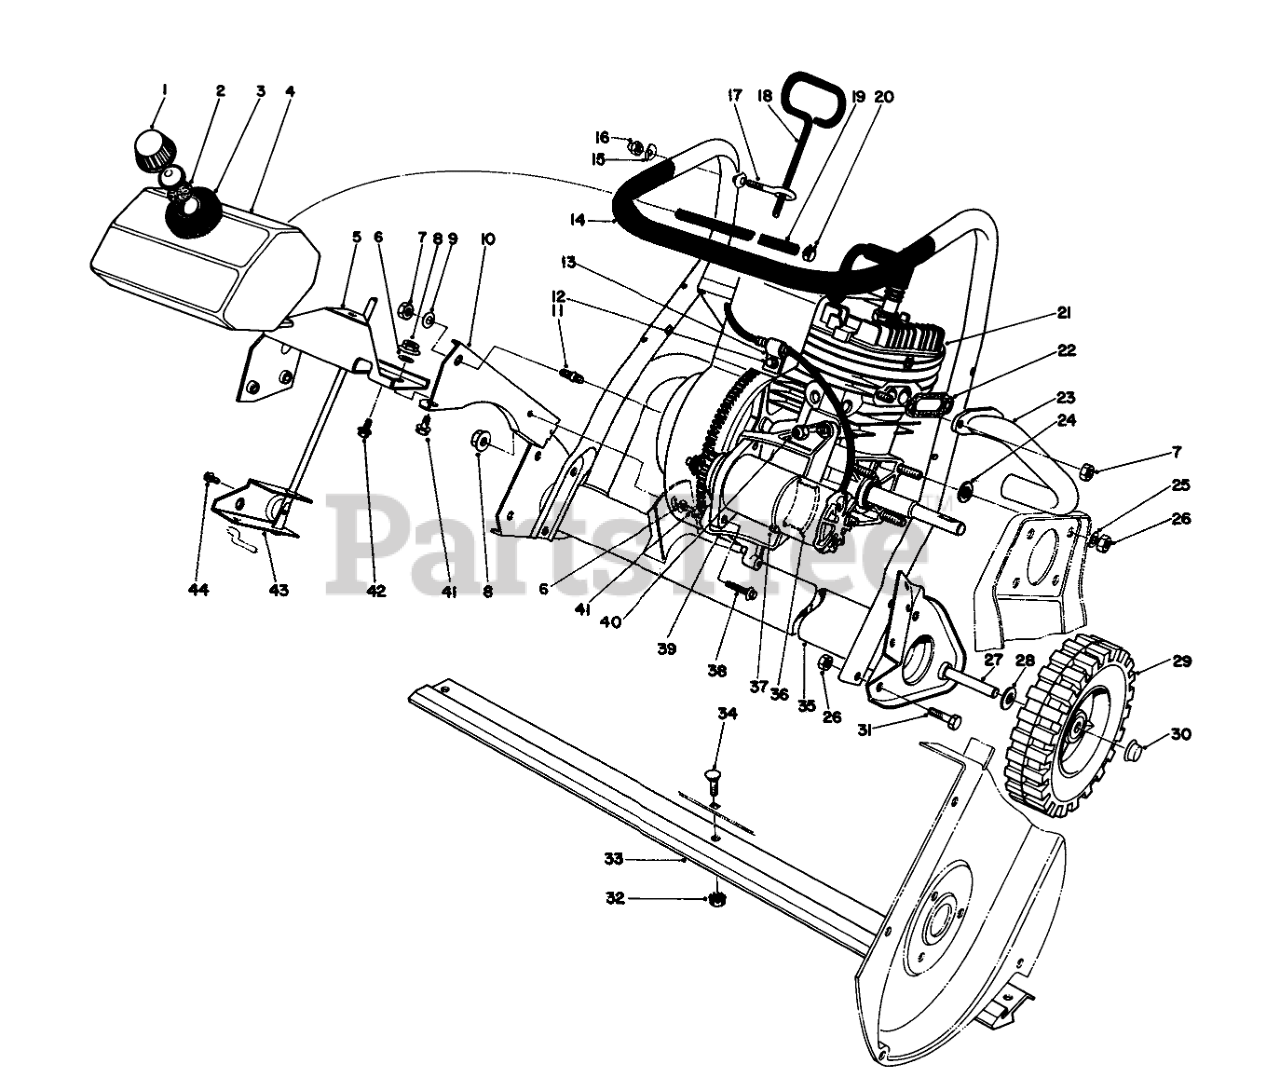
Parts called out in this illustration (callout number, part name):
1	GAS CAP ASM
2	GAS CAP GASKET
3	FOAM PAD
4	GAS TANK
5	Support-Gas Tank
6	WASHER-LOCK
7	NUT-LOCK, CONE
9	GRILLE HINGE SPACER
10	ENGINE SUPPORT
12	SCREW-HWH
13	CABLE CLAMP
14	Lower Handle
15	WASHER
16	NUT-CAP
17	EYEBOLT
18	ADJ ROD ASM
19	GasLine
20	Clamp
21	Engine
22	EXHAUST GASKET
23	EXHAUST PIPE
24	WASHER-FLAT
25	WASHER-PLAIN
26	NUT-LOCK, NI
28	WASHER-FLAT
29	WHEEL
30	RETAINER-PUSH ON
31	SCREW-HH
32	NUT-KEPS
33	SCRAPER
34	BUTTON HD CARR SCR
35	MUFFLER ASSEMBLY
36	RR MOTOR SUPPORT
37	TIE-CABLE
38	SCREW-FLOW, TAPTITE
39	MOTOR MTG BRKT
40	NUT-LOCK, NI
41	5/16-18X.62 WHIZLOK SCR
42	SCREW-HWH
43	VANE ADJ BRKT
44	SCREW
